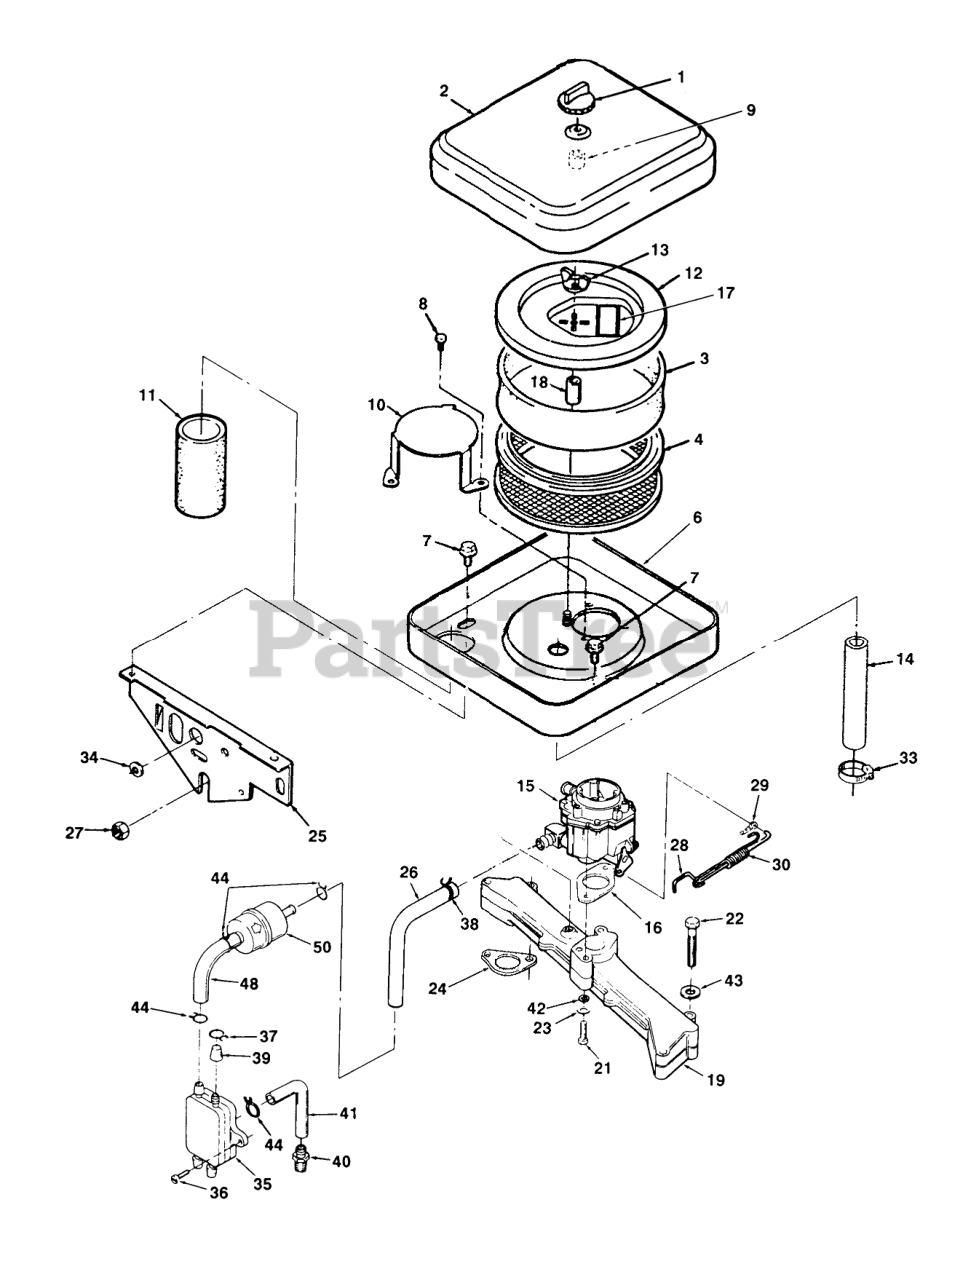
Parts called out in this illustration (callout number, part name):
1	Kit-Float (Incl. Float, Pin, & Valve)
2	Kit-Repair (Incl. Screw & Plug Package, Gasket Package, Float Valve, Idle Adjustment Needle & Spring, Mounting Gaskets, & Idle Limit Cap)
3	GASKET-CARBURETOR
4	JET-FIXED, HIGH ALTITUDE
5	JET-IDLE
6	JET-POWER
8	Solenoid-Fuel Cut-Off (Incl. Gasket)
10	Kit-Choke Shaft (Incl. Choke Valve, Valve Set Screw, & Air Filter)
11	Kit-Choke Lever (Incl. Choke Lever Ring, Choke Spring, & Choke Collar)
12	Kit-Throttle Shaft (Incl. Valve Set Screw, Air Filter, & Throttle Valve)
